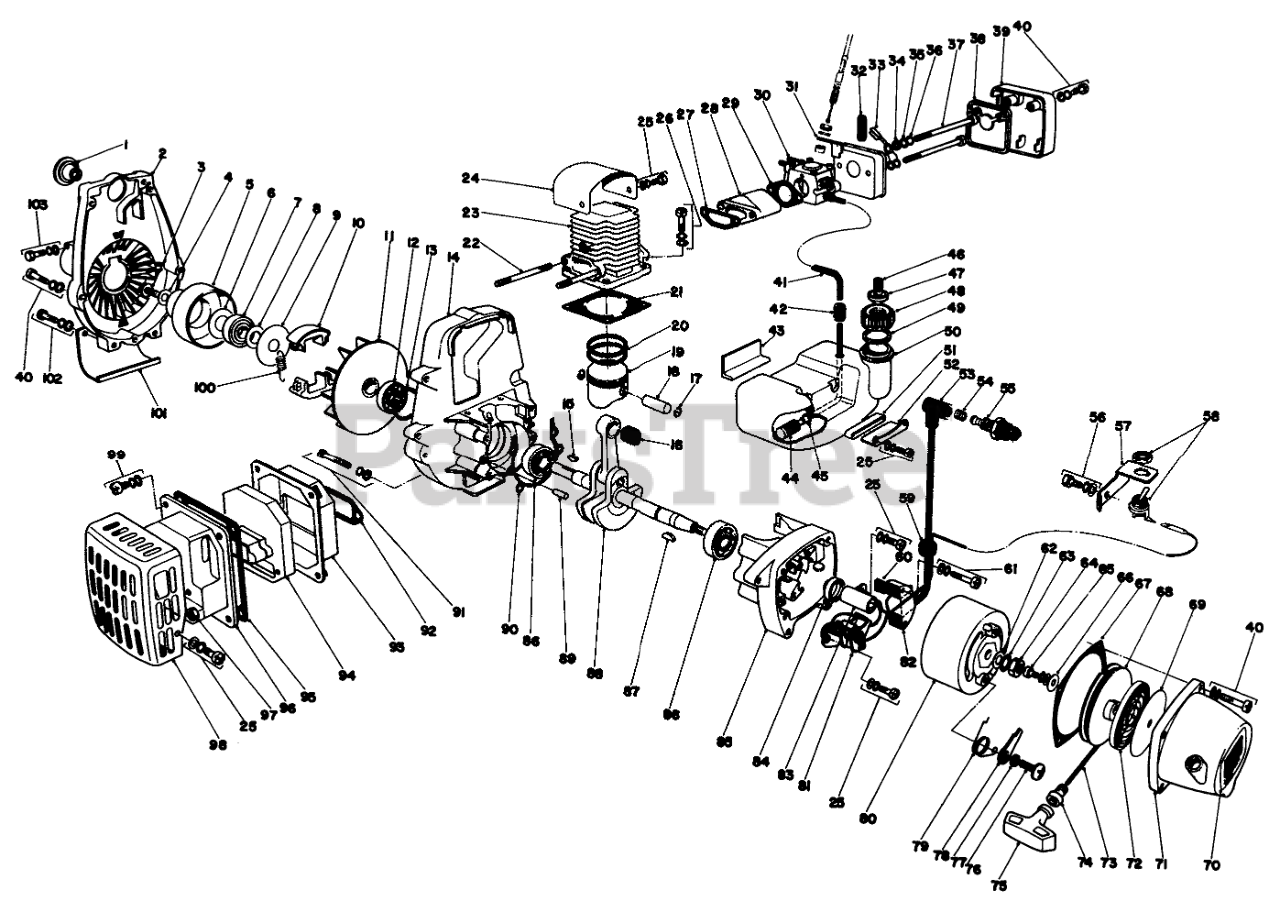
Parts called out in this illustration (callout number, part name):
1	Boot, Plug Cap
2	Fan Cover
4	Washer
5	Clutch Drum
6	Spacer
7	Ball Bearing
8	Spacer
9	Side Plate
10	CLUTCH SHOE
12	Oilseal
13	Circlip
14	Crankcase Set (Incl. Ref. #85)
15	Woodruff Key
16	Needle Bearing
17	Circlip, Piston Pin
18	Piston Pin
19	Piston
20	PISTON RING
21	Gasket, Cylinder Base
22	Stud Bolt
23	Cylinder
24	Cylinder Cover
25	SCREW
26	Screw
27	GASKET
28	Insulator
29	Gasket
30	Carburetor Assembly
31	Case, Air Cleaner
32	GROMMET
33	Choke Shutter
34	Spacer
35	WASHER
36	Washer
38	AIR FILTER
39	AIR CLEANER COVER
40	SCREW
41	FUEL PIPE
42	GROMMET
43	Cushion
44	Fuel Strainer
45	Washer
46	Filter
47	Check Valve
48	Cap-Fuel Tank
49	FUEL TANK CAP GASKET
50	FUEL TANK
51	Cushion
52	Bracket Fuel Tank
53	Cap-Spark Plug
54	Coil Spring-Plug Cap
55	Spark Plug
56	SCREW
57	Bracket, Switch
58	SWITCH STOP
59	Grommet
60	Oiler
61	Screw
62	Washer
63	Spring Washer
65	SCREW
66	Washer
67	Gasket, Starter Case
68	RECOIL DRUM
69	SIDE PLT
70	Decal Commercial Duty
71	Starter Case
72	REWIND SPRING
73	Starter Rope
74	Rope Guide
75	Starter Handle
76	Screw
77	RATCHET SPACER
78	Ratchet
79	Ratchet Spring
80	Flywheel
81	CONTACT BREAKER SET
82	IGNITION COIL
83	CONDENSER
84	Oilseal
86	Bearing
87	Woodruff Key
88	Crankshaft Assembly
89	Knockpin
90	Gasket, Crankcase
91	SCREW
92	Gasket, Muffler
93	Muffler Body
94	Silencer
95	Gasket
96	Muffler Lid
98	Muffler Cover
99	Screw
100	CLUTCH SPRING
101	Bracket
102	SCREW
